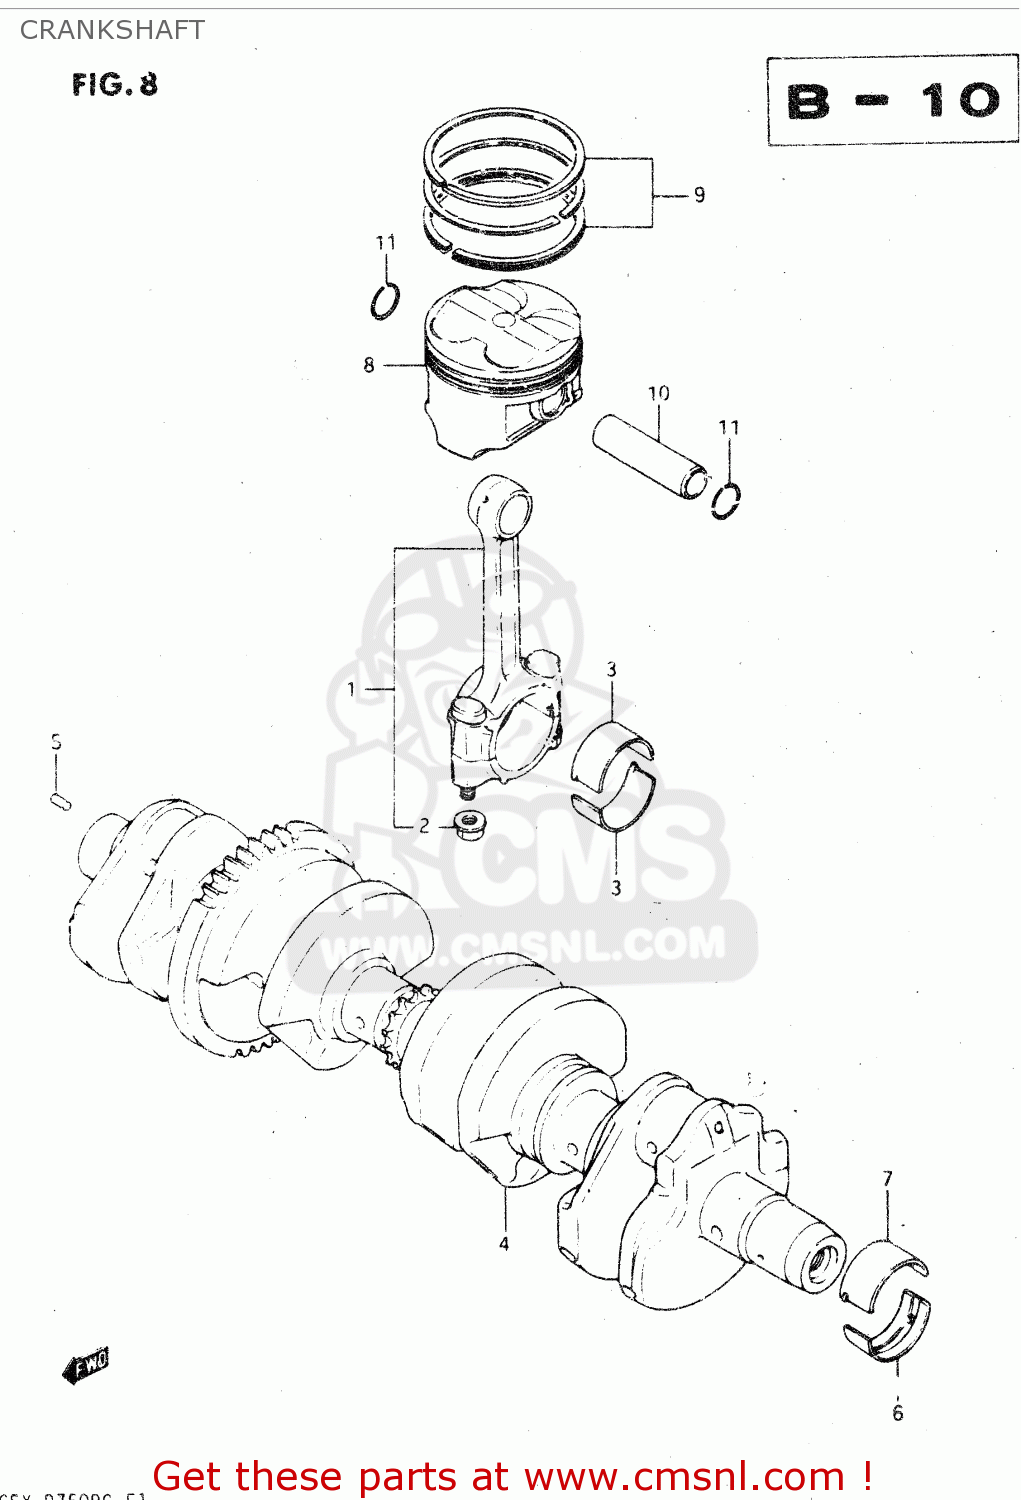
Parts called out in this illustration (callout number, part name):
1	ROD ASSEMBLY,CONNECTING
2	NUT
3	BEARING,CRANK PIN
4	CRANKSHAFT
5	PIN
6	BEARING,CRANKSHAFT LWR
7	BEARING,CRANKSHAFT UPR
8	PISTON
9	RING SET,PISTON
10	PIN,PISTON
11	CIRCLIP
